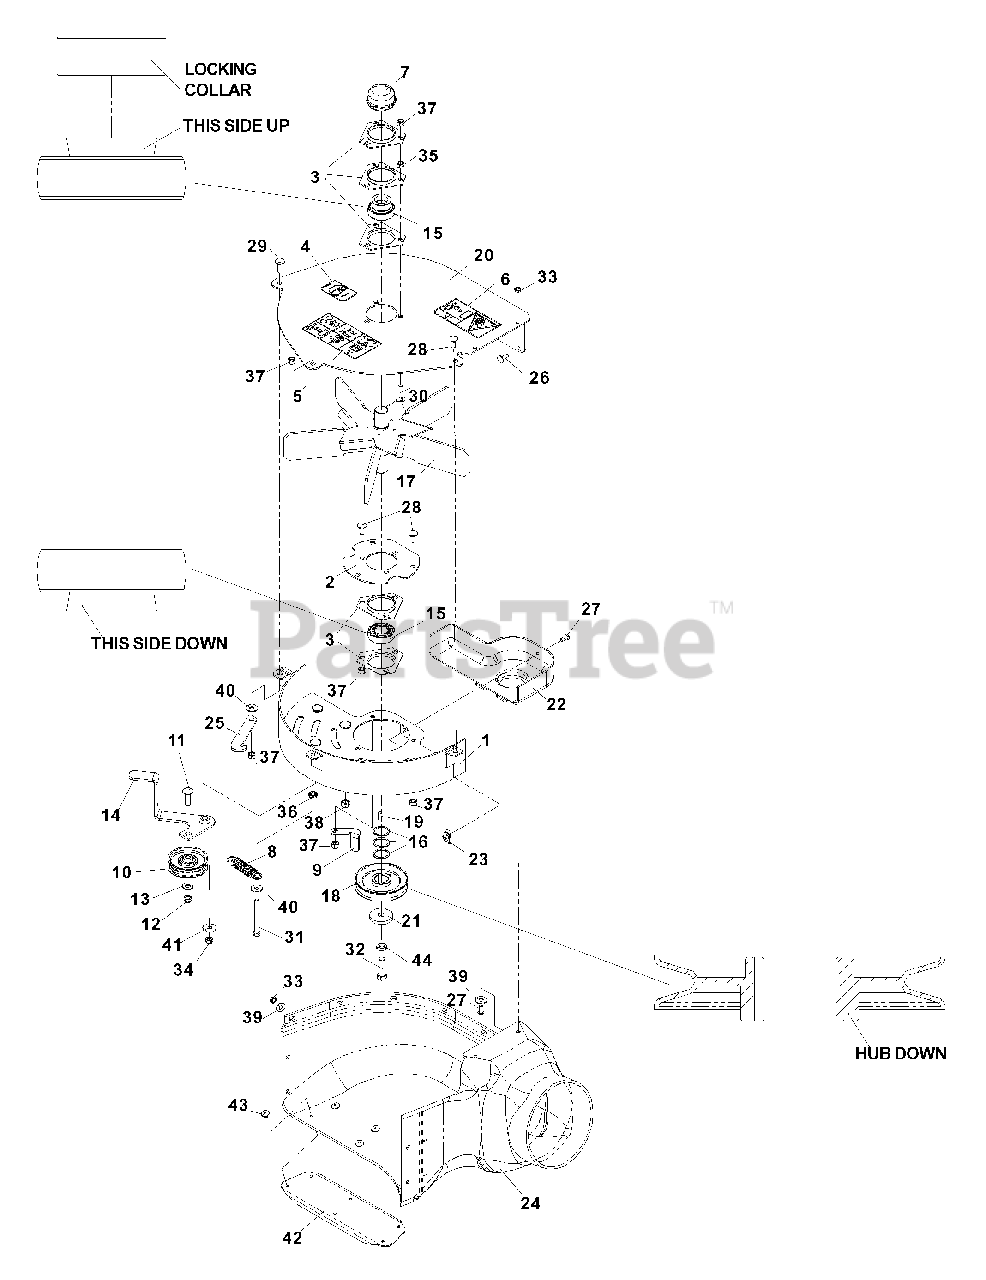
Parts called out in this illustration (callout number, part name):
1	FLOOR WELDMENT
2	BEARING PLATE
4	DECAL, NO STEP
5	DECAL, WARNING
6	DECAL, SEVERING
7	GREASE CAP
9	BELT GUIDE
11	RHSNB, 3/8 -16 x 1 1/2,
12	NUT, 3/8 -16, JAM NYLOC
13	WASHER, 3/8 , SAE
16	BUSHING, MACHINE, 18 GA
17	FAN WELDMENT
18	SHEAVE, 4"
21	WASHER, HEAVY
22	PULLEY SHIELD
23	RETAINER, 1/4C, "U" TYPE
24	BLOWER HOUSING
25	KEEPER, IDLER
26	RHSNB, 1/4-20 x 1/2, GR2
27	SCREW, 1/4-20 x 5/8, SKT HD
28	RHSNB, 5/16 -18 x 3/4,
29	RHSNB, 5/16 -18 x 1,
30	RHSNB, 5/16 C x 1 1/4
31	HCS, 5/16 -18 x 2 3/4,
32	HCS, 7/16 -20 x 1 1/2,
33	NUT, 1/4C, THIN NYLOC
34	NUT, 3/8 -16, CENTERLOCK
35	NUT, 5/16 C
36	NUT, 5/16 C
37	NUT, 5/16 C, NYLOC
38	NUT, 3/8C, NYLOC
39	WASHER, 1/4
40	WASHER, 5/16
41	WASHER, 3/8
42	BLOWER SUPPORT
44	LOCKWASHER, 7/16
